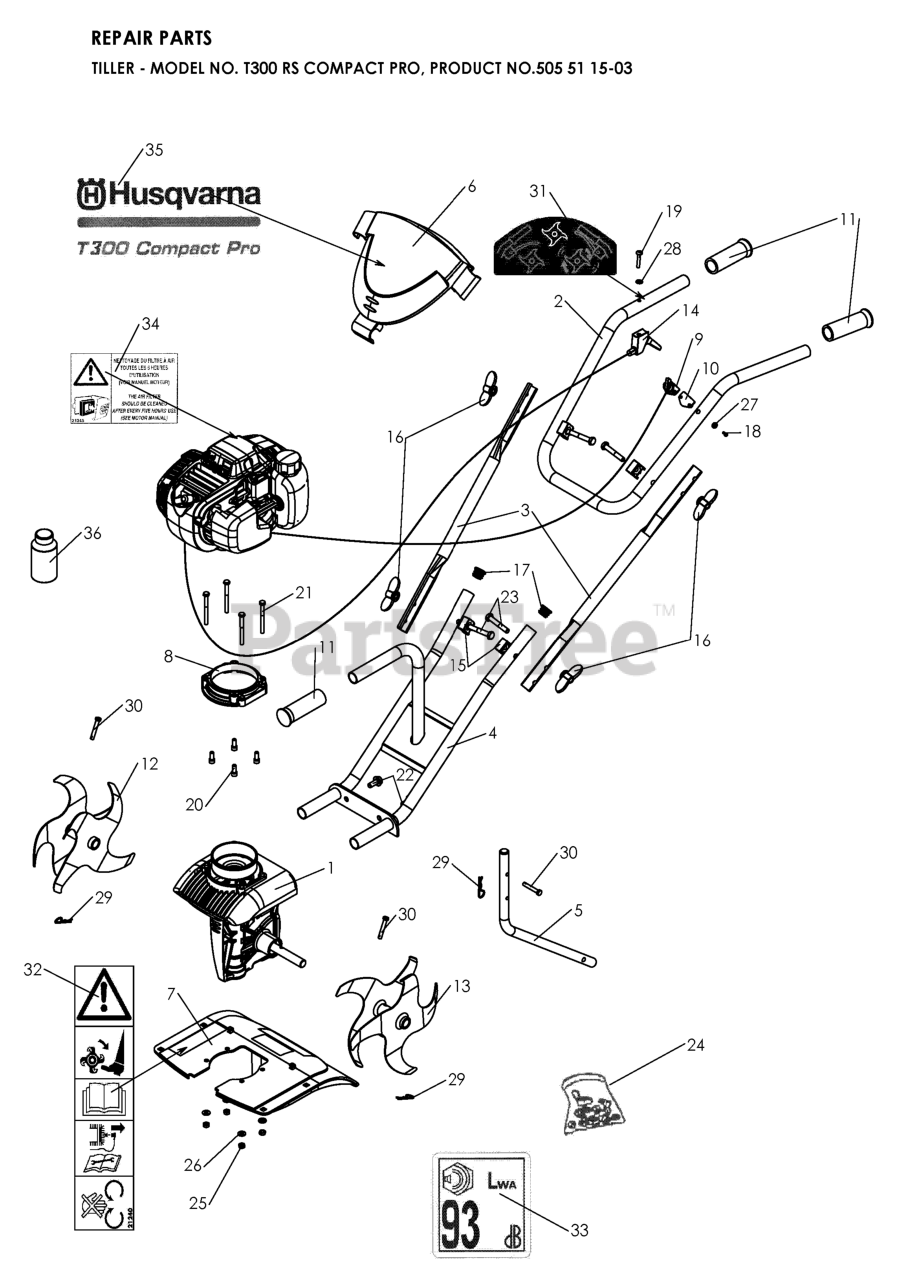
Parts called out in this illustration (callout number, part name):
10	SUPPORT SWITCH
18	SCREW 0300080301
25	Blocking nut M 6 Z
29	COTTER PIN
